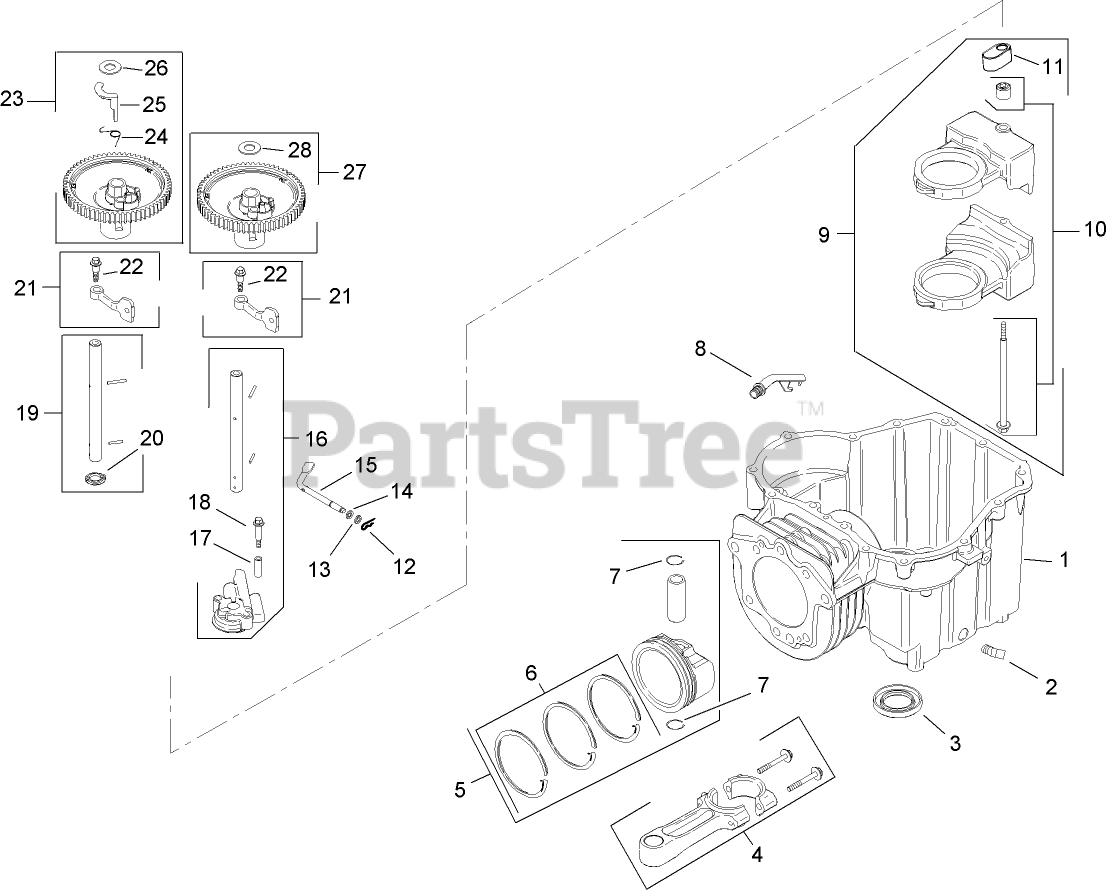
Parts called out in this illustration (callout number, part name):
1	Loose Parts Package
2	PLUG-PIPE, SQ HD (3/8)
3	Seal-Oil
4	Connecting Rod ASM
5	Piston w/Ring Set (94 mm) (Includes 6-7)
6	Ring Set (94 mm)
7	Retainer-Pin, Piston
8	Tube-Back, Drain
9	Balance Weight Kit (Includes 10-11)
10	Screw and Guide Pin Kit
11	Shoe-Guide
12	Clip-Pin, Hitch
13	WASHER-FLAT (6mm)
14	WASHER-FLAT (1/4)
15	Shaft-Cross, Governor
16	Oil Pump ASM (Includes 17-18)
17	Spacer-Screw, Oil Pump
18	Screw-Pump, Oil
19	Shaft-Cam, Center - Exhaust (Includes 20)
20	Washer-Thrust
21	Cam Lever ASM (Includes 22)
22	Bolt-Shoulder (M6x1x26)
23	Cam Gear ASM - Intake (Includes 28)
24	Spring-A C R
25	Weight-A C R
26	Washer-Thrust, A C R
27	Cam Gear ASM - Intake (Includes 28)
28	Washer-Thrust, A C R
